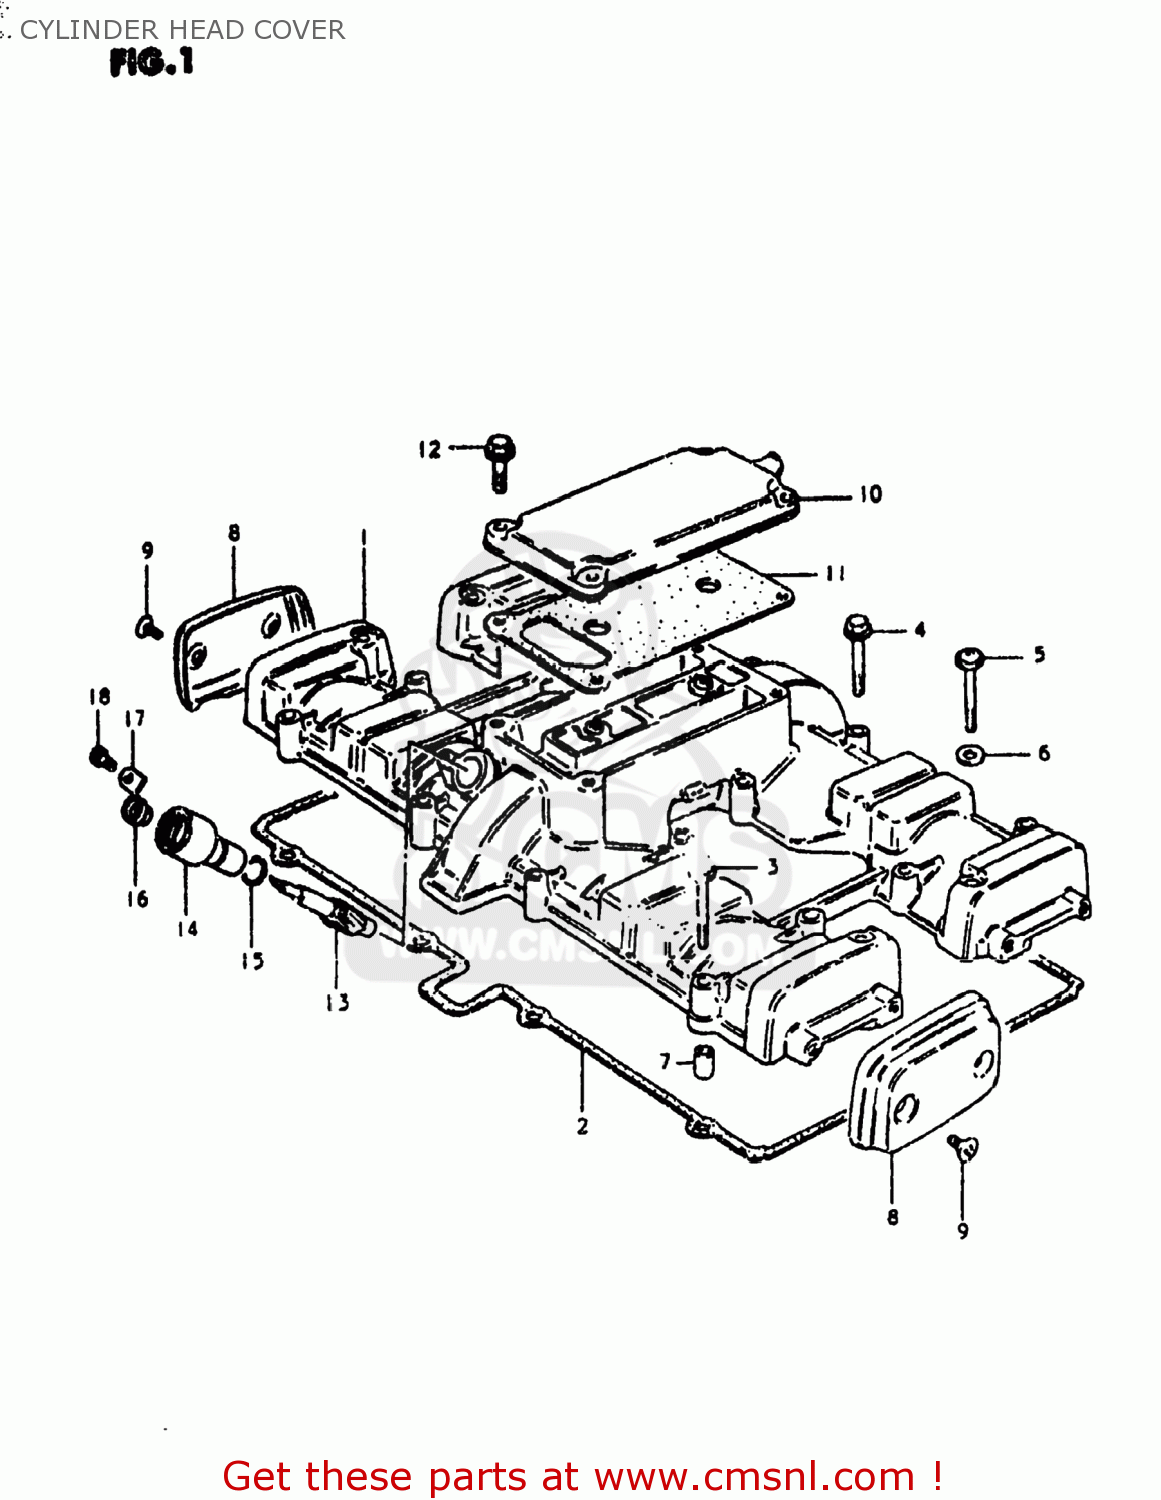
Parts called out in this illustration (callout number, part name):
1	COVER,CYLINDER HEAD
2	GASKET,CYLINDER HEAD COVER (MCA)
3	BOLT
4	BOLT 6X35
5	SCREW 6X40
6	GASKET (NAS)
7	PIN(6.2X8X11)
8	CAP,CYLINDER HEAD COVER
9	SCREW 5X12
10	COVER,BREATHER
11	GASKET (MCA)
12	BOLT,REAR
13	GEAR,TACHOMETER DRIVEN
14	SLEEVE,TACHOMETER DRIVE
15	SEAL,TACHOMETER DRIVEN
16	SEAL,OIL(5X12X8)
17	PLATE,TACH DRIVE GEAR SLEEVE
18	SCREW(5X12)
